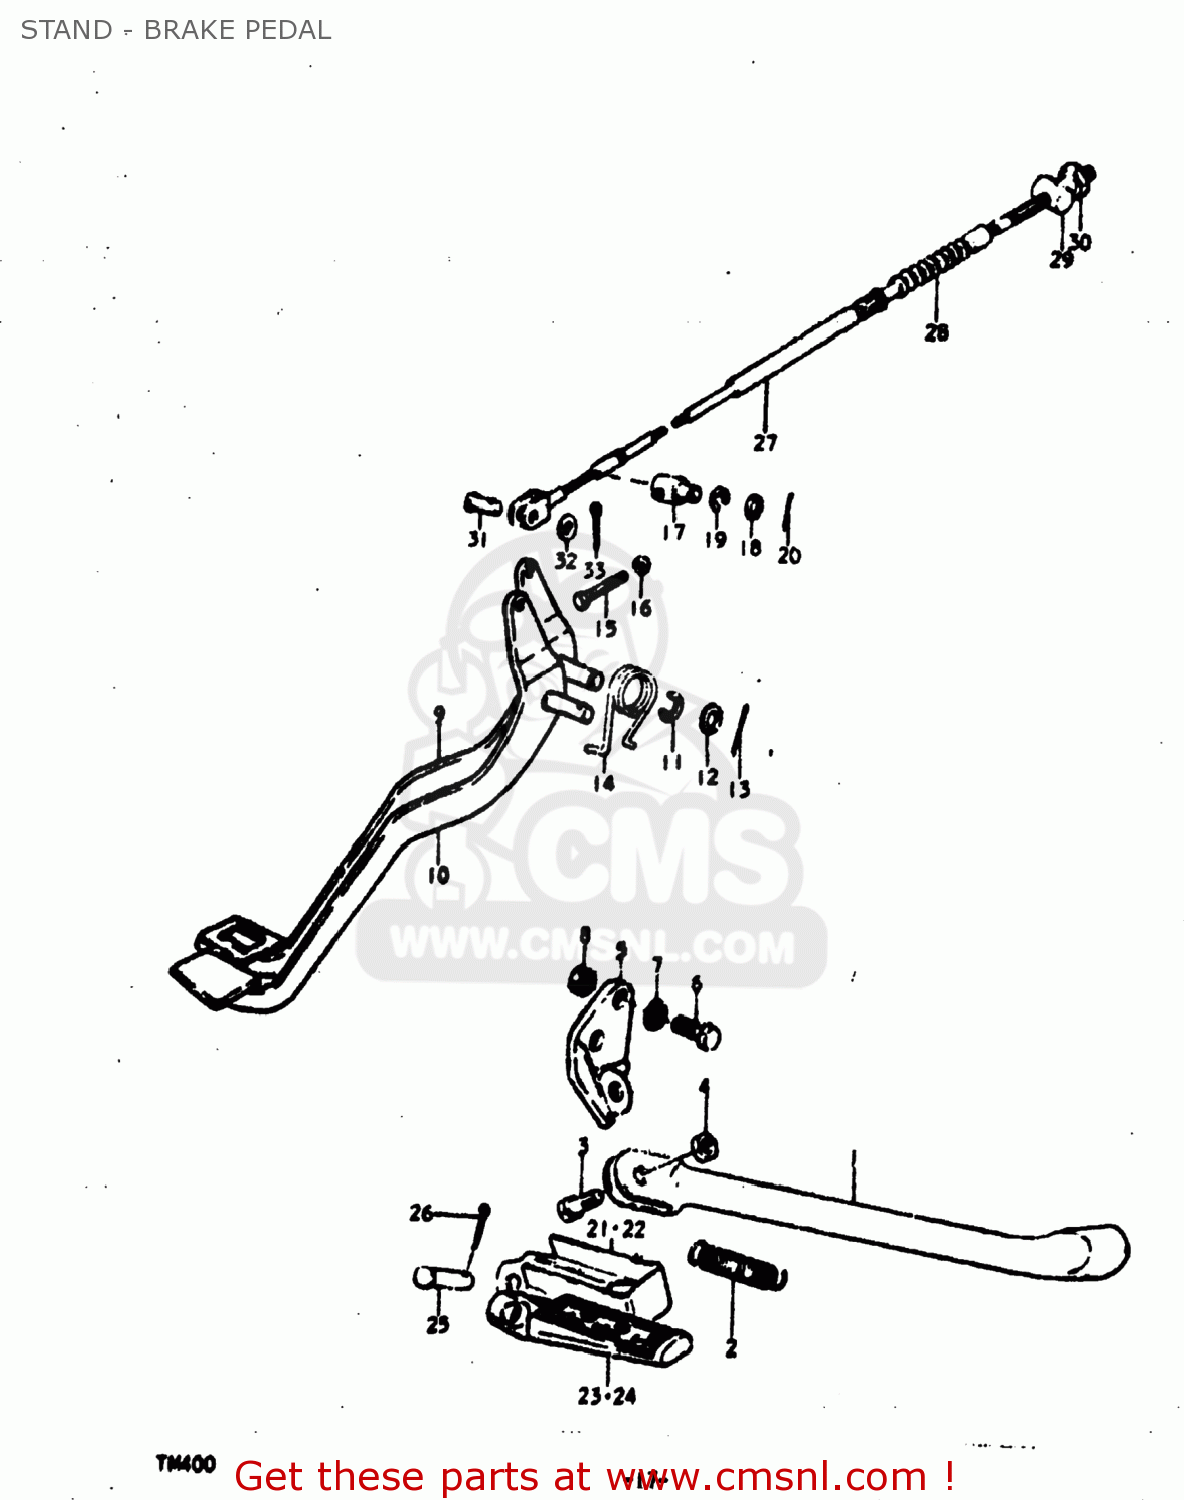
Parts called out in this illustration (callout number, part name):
1	STAND,SIDE
2	SPRING
3	BOLT
4	NUT
5	BRACKET,SIDE STAND
6	BOLT 10X25
7	LOCK WASHER
8	NUT
9	PEDAL,BRAKE
10	PEDAL,BRAKE
11	E RING 8MM
12	WASHER
13	PIN 30X20
14	SPRING
15	BOLT
16	NUT
17	PROP STAND
18	WASHER
19	E RING 6MM
20	PIN 25X20
21	FOOTREST,FRONT,RIGHT
22	FOOTREST,FRONT,LEFT
23	BAR,FRONT FOOTREST
24	BAR,FOOTREST,LEFT
25	PIN
26	PIN
27	CABLE,RR BRAKE
28	SEAL,DUST
29	PIN
30	NUT
31	PIN(L:13.5)
32	WASHER
33	PIN
